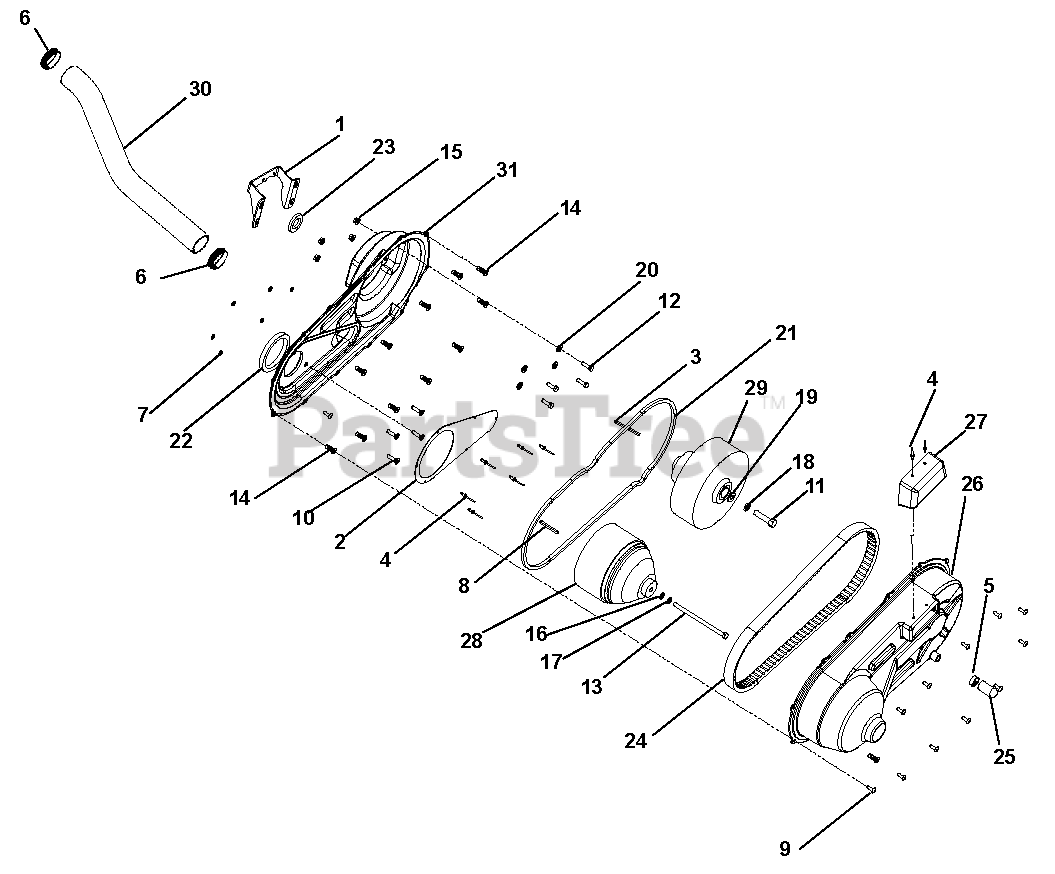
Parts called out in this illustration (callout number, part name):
1	BRACKET, CVT COVER TO TRANS.
2	COVER, CVT INLET DUCT
3	KEY 3/16 X 3
4	RIVET POP 3/16 .126-.250
5	SPRING CLAMP 1" OD HOSE
6	CLAMP, HOSE,WRM DRV,1.81 X 2.75
7	RIVET POP WASHER 3/16
8	KEY, .187 X .247 X 2.5 LG
9	SCREW, MCH .25-20 X .75 TXTR
10	BOLT, 5/16-24 X .75 HSFHCS (Apply Loc-Tite?)
11	BOLT, HEX .50-20 X 2.00 GR5 YWZC
12	BOLT, HEX .31-18 X 1 GR5 YWZC
13	HHCS 3/8-24 X 6 1/2 GR5 PLT
14	INSERT, 1/4-20 ARS4-420-280
15	NUT, TOP LOCK FLANGE .312-18 YWZC
16	WASHER, FLAT .406 X .812 X .065 YWZC
17	WASHER, LOCK .38 X .094 REG YWZC
18	WASHER, LOCK .50 X .125 YWZC
19	WASHER, FLAT .531 X 1.06 X .095 YWZC
20	WASHER, FLAT 5/16 NEOPRENE PLT
21	SEAL, MAIN TRUCK CVT HOUSING
22	GASKET, CVT, FOAM
23	SEAL, CVT TO TRANSAXLE
24	BELT, CVT Ð LP3
25	CAP, DRAIN 7/8 OD PORT
26	ENCLOSURE, CVT OUTER
27	OUTLET DIVERTER, CVT
28	DRIVER, POWERBLOC Ð LP3
29	DRIVEN, CVTECH POWERBLOC Ð LP3
30	HOSE, CVT AIR INTAKE
31	CVT SHROUD, INNER
